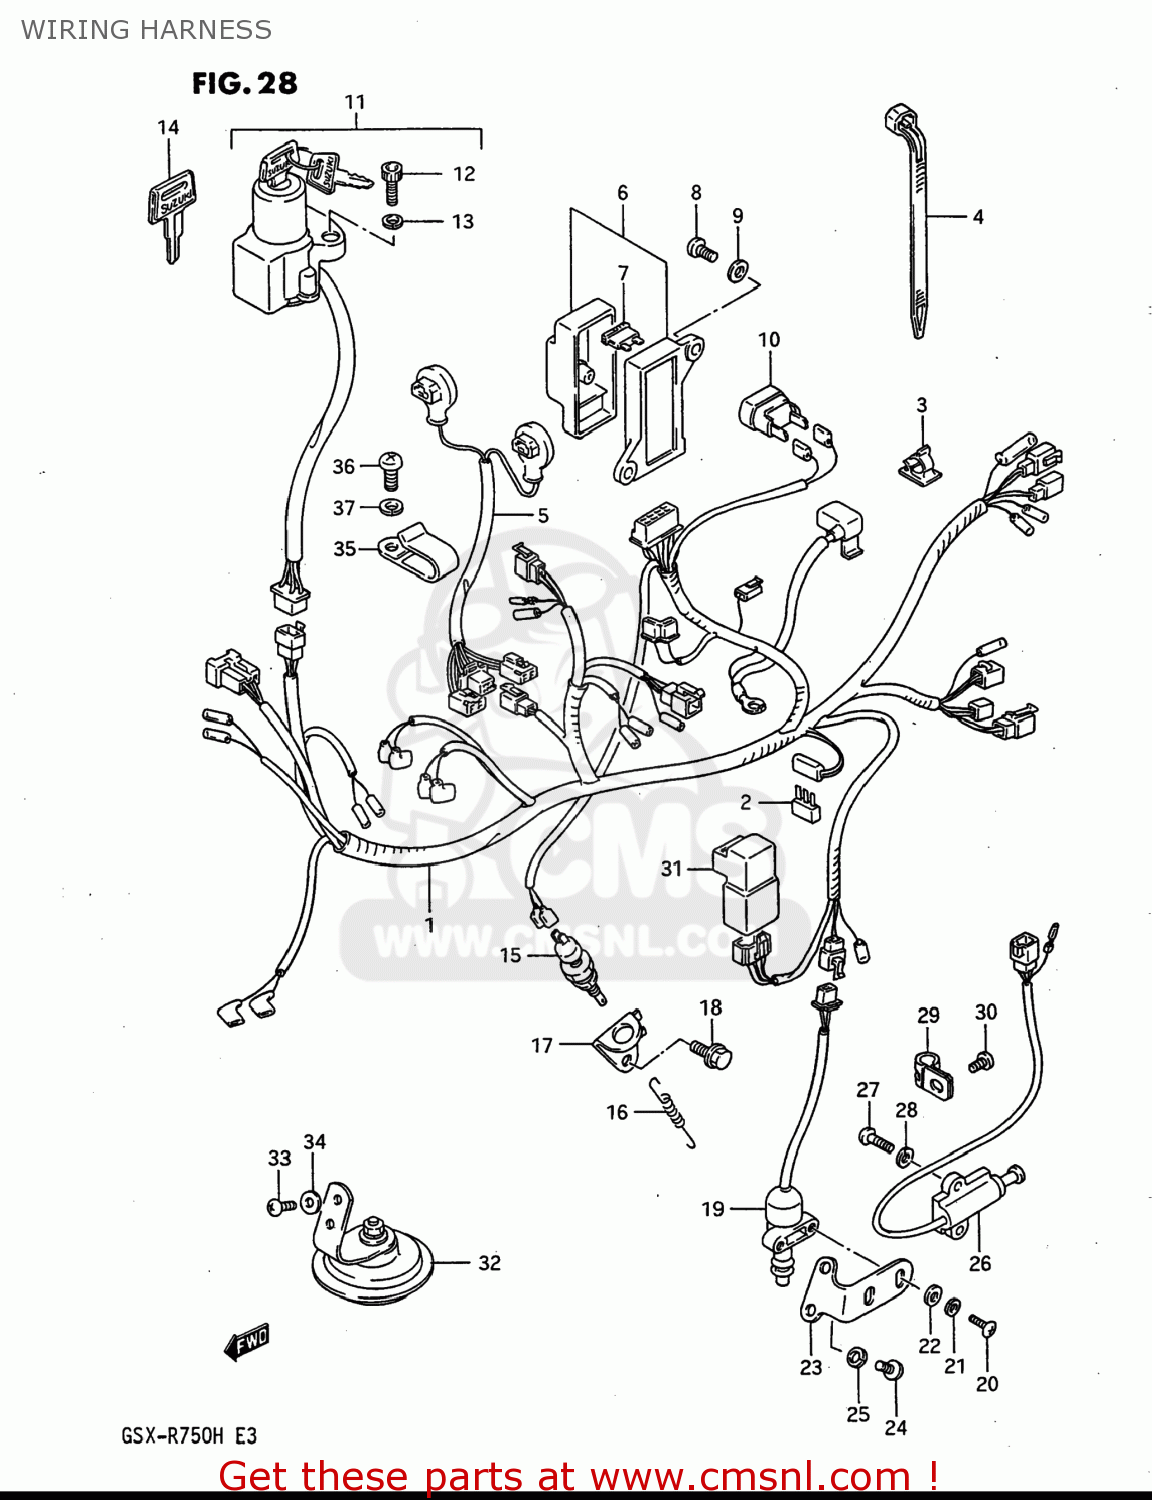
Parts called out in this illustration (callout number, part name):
1	HARNESS,WIRING
2	DIODE(STANLEY DE8804)
3	CLAMP
4	CLAMP
5	WIRE
6	BOX ASSEMBLY,FUSE
7	FUSE(10A)
8	SCREW 6X12
9	WASHER
10	BREAKER ASSY,CIRCUT
11	SWITCH ASSY,IGNITION
12	BOLT
13	WASHER,LOCK
14	KEY,BLANK
15	SWITCH ASSY,STOP LAMP
16	SPRING
17	BRACKET,STOP LAMP SWITCH
18	BOLT
19	SWITCH ASSY,SIDE STAND WARN
20	SCREW 5X20
21	WASHER,LOCK
22	WASHER,5MM
23	BRACKET,PROP STAND WARNING
24	SCREW 6X12
25	WASHER,LOCK
26	SWITCH ASSEMBLY,SIDE STAND
27	SCREW
28	WASHER,LOCK
29	CLAMP
30	SCREW
31	RELAY ASSEMBLY
32	HORN ASSY
33	SCREW
34	WASHER
35	CLAMP,HANDLE SWITCH LEVER
36	SCREW
37	WASHER,LOCK
